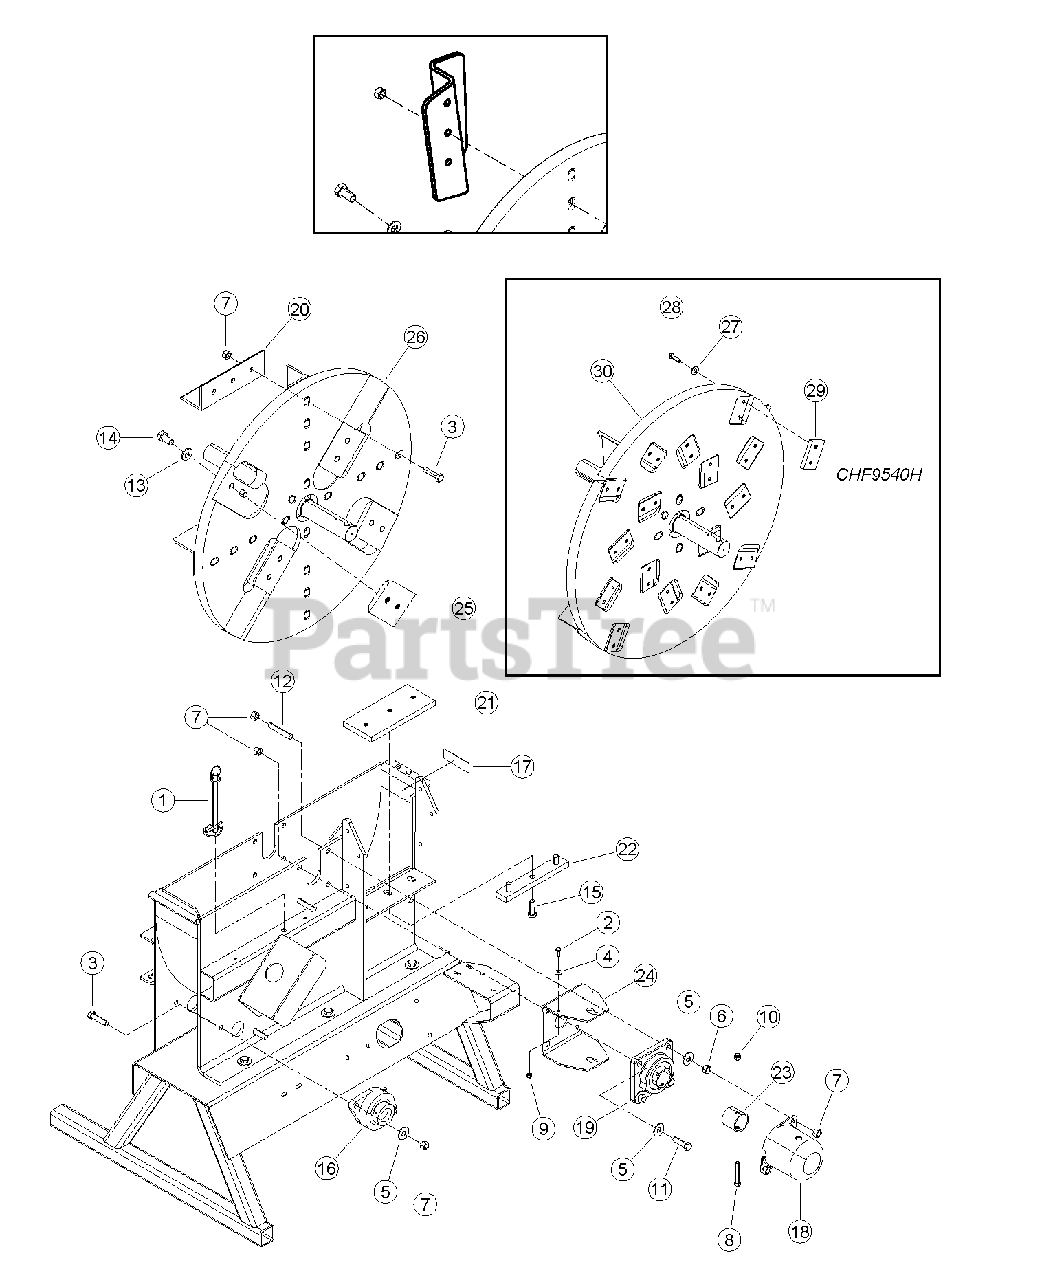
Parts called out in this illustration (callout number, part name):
27	WASHER, 5/16 GR8 USS FLAT
28	BOLT, 5/16 X 1-1/4 HEX HD GR8 PATCH
28	BLADE, TWO EDGE TOOL STEEL
29	BLADE, KIT
30	ASSEMBLY, CHIPPER DISK
